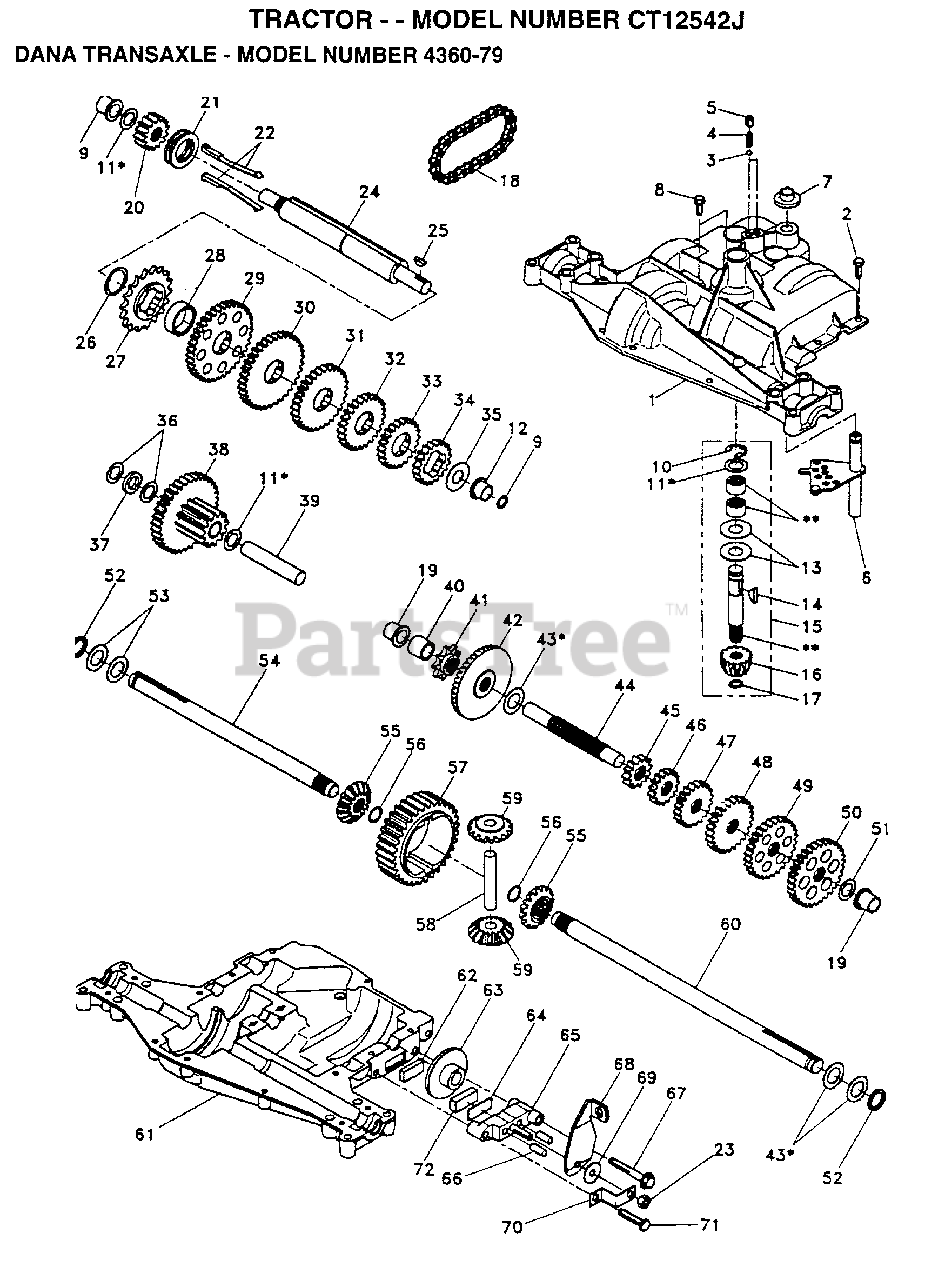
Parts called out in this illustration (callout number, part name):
1	HOUSING UPPER TRN
4	"SPRING, DETENT LT"
5	"SCREW, SET LT"
6	KIT SHIFTER ASM
7	SHIFTER BOOT
8	SCREW TAP W/SEAL
9	SQUARE RING
11	ASM KIT SHIM 4689
12	BEARING FLAN-DANA
13	WASHER T
14	KEY WOODRUFF-DANA
15	AS KIT INPUT SHFT
16	PINION 14T T
17	"RING,RETAINING LT"
18	"CHAIN,24 PTCH LT"
19	BEARING.FLNG.5510
20	GEAR SPUR 14 TTH
21	COLLAR CLUTCH
22	ASM KIT CLTCH KEY
23	NUT.LOCK.5/16-24
24	SHAFT INTERM DANA
25	WOODRUFF KEY
26	"RING,RETAINING LT"
27	SPROCKET 18T T
28	SPACER YT
29	GEAR SPUR 37 TTH
30	GEAR SPUR 35 TTH
32	GEAR 25T LT
33	GEAR SPUR 22 TT
34	SPUR GEAR 19T
35	"WASHER, PLAIN LT"
36	WASHER 025
37	SPACER
38	ASSM GEAR COMB
39	SHAFT IDLER
40	SPACER T
41	SPROCKET 9T LT
43	ASM KIT SHIM
44	SHAFT T
45	GEAR SPUR 12 TTH
46	GEAR SPUR 15 TTH
48	"GEAR, SPUR 25T LT"
49	GEAR 28T T
50	"GEAR, SPUR 31T LT"
51	WASHER 060
52	NEOPRENE WASHER
53	WASHER 031
55	GEAR 15T T
56	"RING,RETAINING LT"
58	SHAFT T
59	GEAR 1ST T
61	HOUSING LOWER TNS
62	PUCK T
63	BRAKE DISC. T
64	SPACER LT
66	PIN T
69	WASHER LT
71	"SCREW, TAPPING LT"
72	PUCK T
